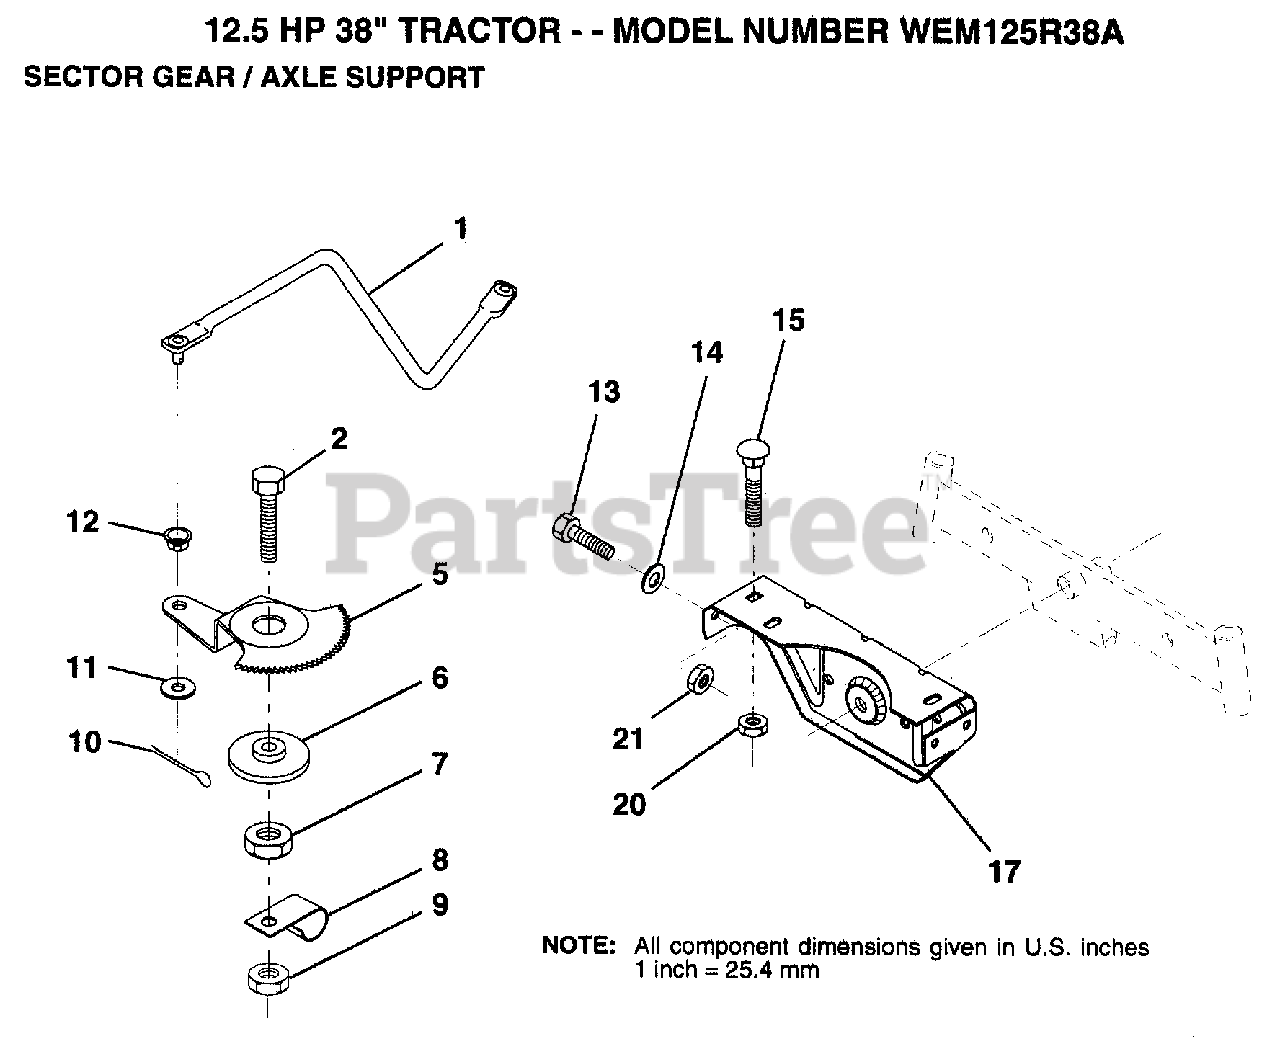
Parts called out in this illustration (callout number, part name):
1	DRAG LINK
2	"BOLT,HEX"
5	GEAR SECTOR
6	BUSHING
7	NUT
8	CLIP INSULATOR
9	NUT LTV
10	COTTER PIN
11	WASHER
12	BUSHING.DRAGLINK
13	BOLT
14	WASHER
15	BOLT
17	SUPT AXLE FRONT
20	NUT
21	NUT
